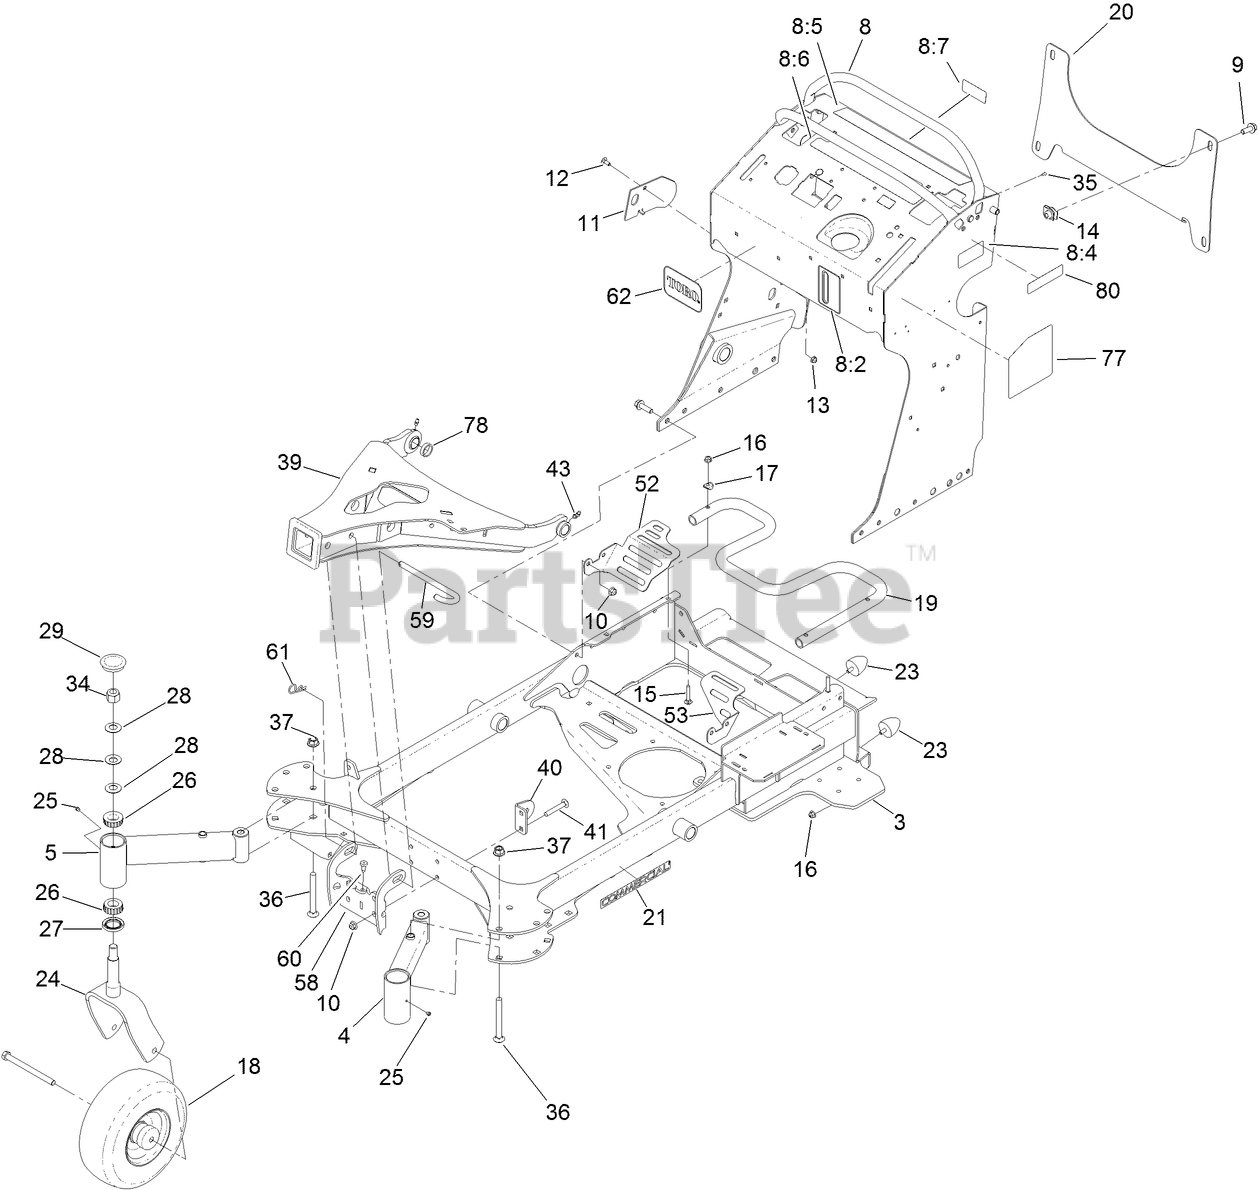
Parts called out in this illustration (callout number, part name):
4	TUBE-CASTOR, SHORT
5	TUBE-CASTOR, LONG
8	TOWER DECAL ASM
8:2	DECAL-LEVEL, OIL
8:4	DECAL-FILL, FUEL
8:5	DECAL-CAUTION
8:6	DECAL-CONTROLS
8:7	DECAL-FUSE
9	SCREW-HHF
10	NUT-HF, NI
11	PLATE-STRIKER
12	SCREW-CARR
13	NUT-HF
14	NUT-TINNERMAN
15	BOLT-CAR
16	NUT-HF, NI
17	WASHER
18	WHEEL/TIRE AND BEARING ASM
19	TUBE-MOUNT, FUEL TANK
20	BRACKET-CROSS
21	DECAL-COMMERCIAL
23	BUMPER-RUBBER
24	FORK-CASTER
26	BEARING-ROLLER, TAPERED
27	SEAL-GREASE
28	WASHER-BELLVILLE
29	CAP-GREASE
34	NUT-LOCK, NI
35	RIVET-POP
36	SCREW-CARR
37	NUT-LOCK
40	BRACKET-CYLINDER
41	SCREW-CARR
43	FITTING-GREASE, 90 DEG
52	GUARD-FAN, RH
53	GUARD-FAN, LH
58	BRACKET-LOCK
59	PIN-HITCH
60	BUMPER-RUBBER
61	PIN-HAIR
62	DECAL-LOGO, TORO
77	DECAL SERVICE-MULTIFORCE
78	SPACER
80	DECAL-ARRESTOR, SPARK
